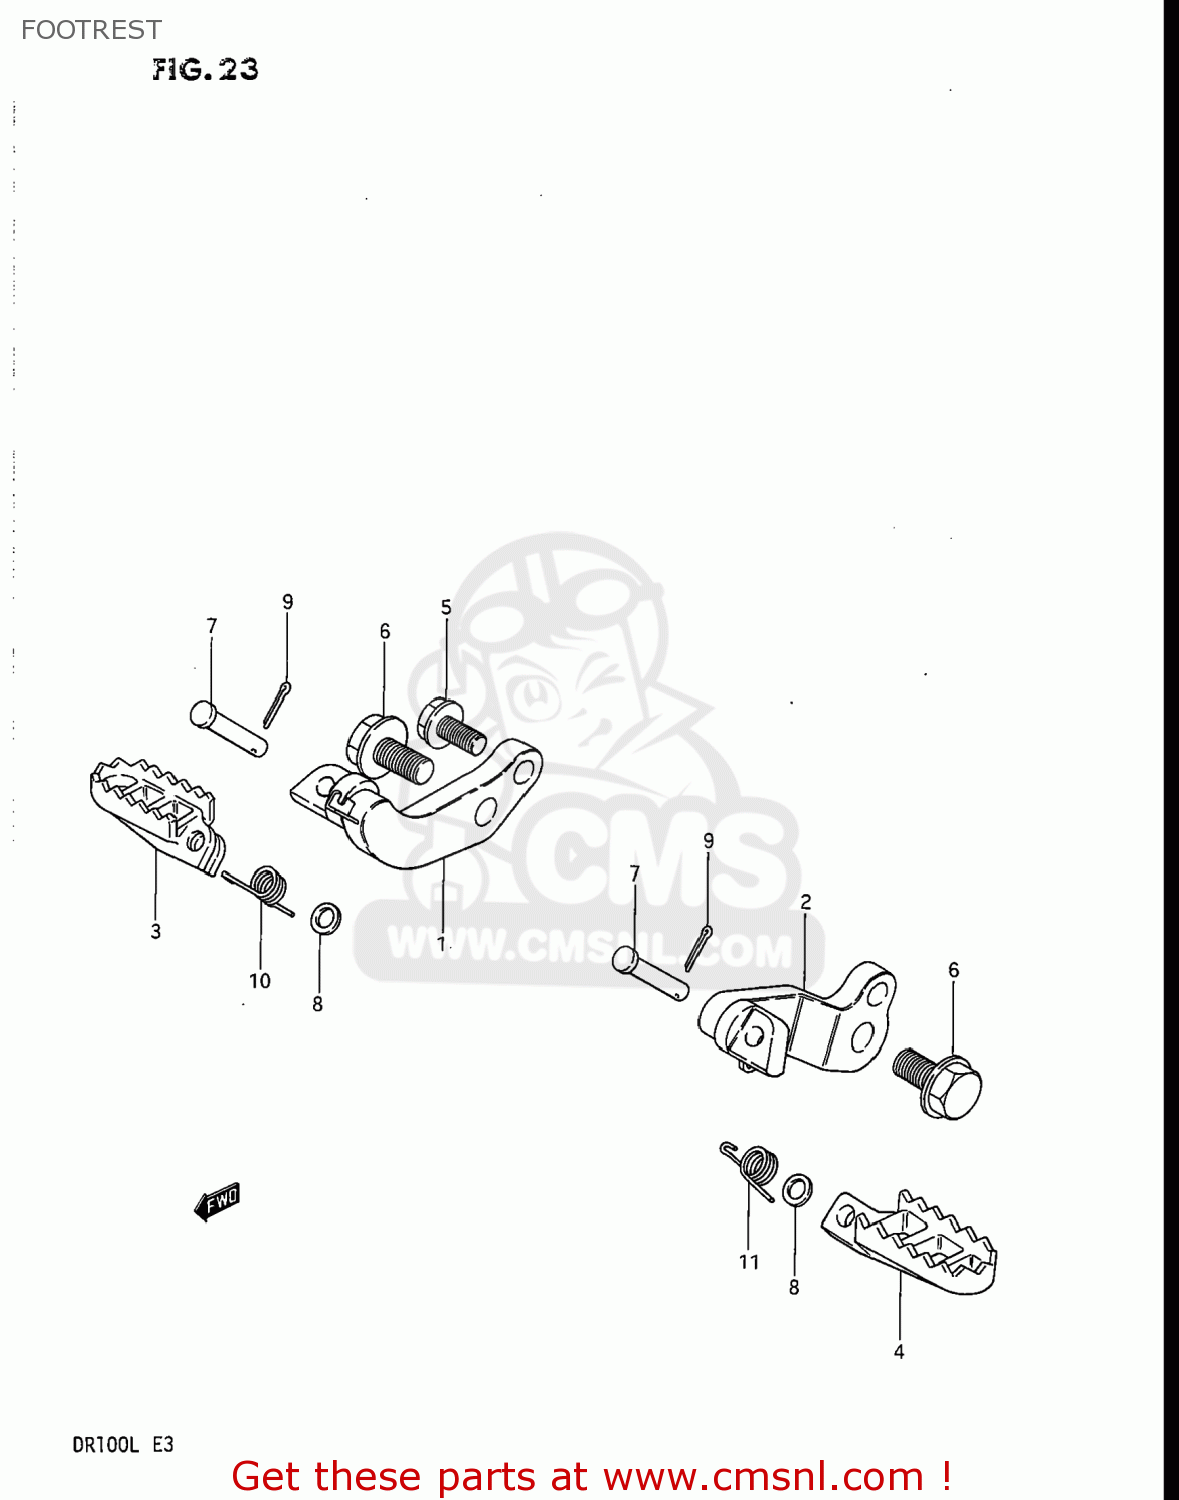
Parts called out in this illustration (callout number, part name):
1	BAR,FRONT FOOTREST
2	BAR,FRONT FOOTREST,LEFT
3	FOOTREST
4	FOOTREST
5	BOLT,LOWER
6	BOLT
7	PIN
8	WASHER
9	PIN 20X20
10	SPRING
11	SPRING,FOOTREST,LEFT
